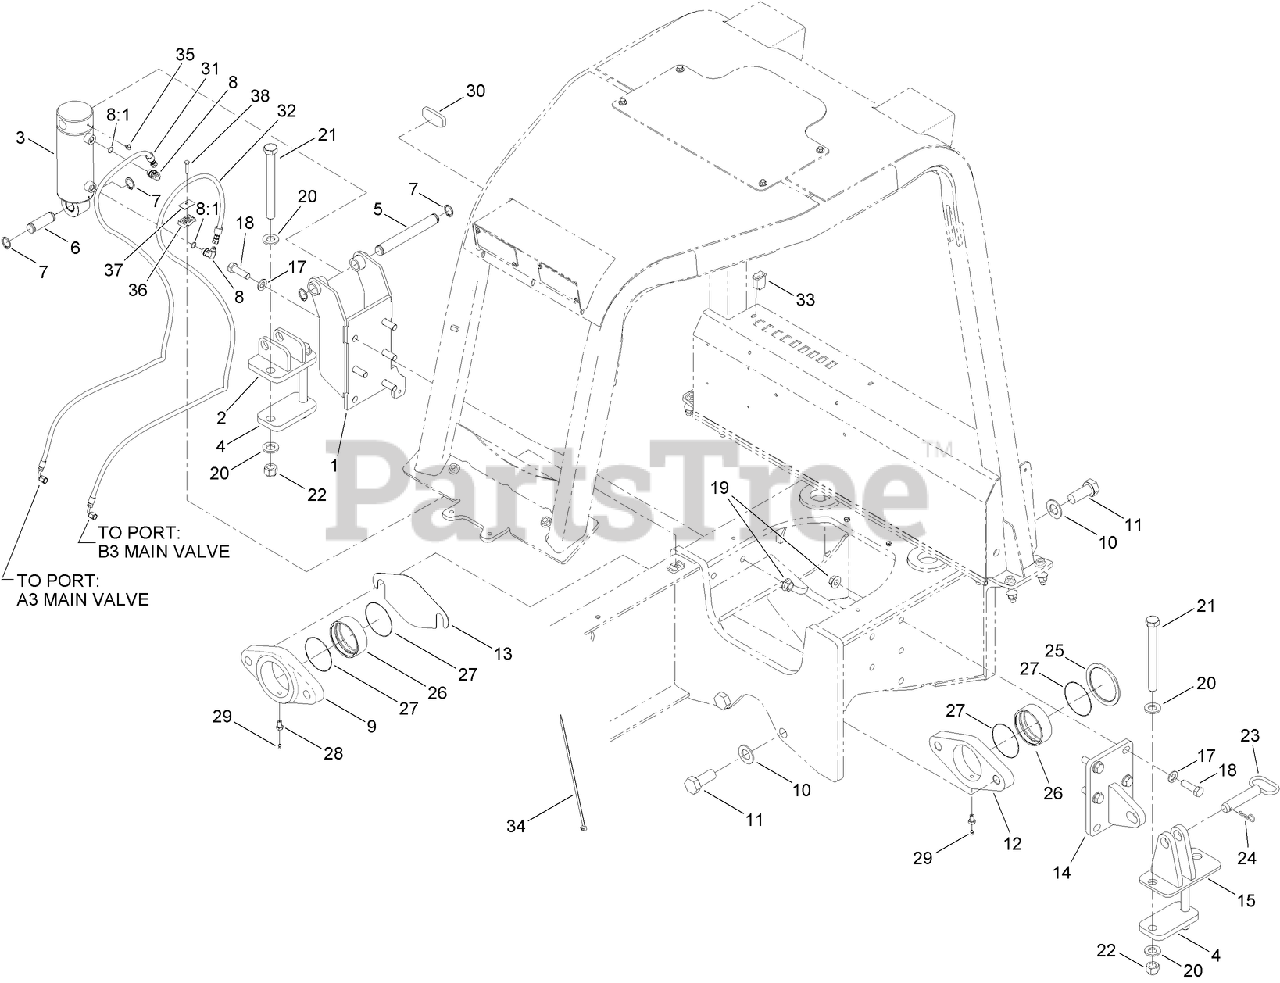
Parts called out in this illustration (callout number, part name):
1	MOUNT-CYLINDER, FRAME
2	MOUNT-AXLE, REAR
3	HYD CYLINDER ASM
4	PLATE-MOUNTING
5	PIN-PLOW
6	PIN-CLEVIS
7	RING-RETAINING, EXTERNAL
8	FITTING-ELBOW, 90 DEG
8:1	O-RING
9	HOUSING-MOUNT, TRUNION
12	HOUSING-MOUNT, TRUNION
13	SHIM-MOUNT, AXLE
14	LOCKOUT-FRAME
15	LOCKOUT-AXLE
18	SCREW-HH
19	NUT-HHF
21	SCREW-HH
22	NUT-HH
24	PIN-Hair
25	WASHER-THRUST
26	BUSHING-PIVOT
28	ADAPTER-LOCATING
29	FITTING-GREASE
30	METER-SLOPE
31	HYD HOSE ASM
32	HYD HOSE ASM
33	SWITCH-ROCKER, 2 POLE
34	TIE-CABLE
35	FITTING-GREASE, 90 DEG
36	CLAMP-TUBE
37	COVERPLATE
38	SCREW-HH
